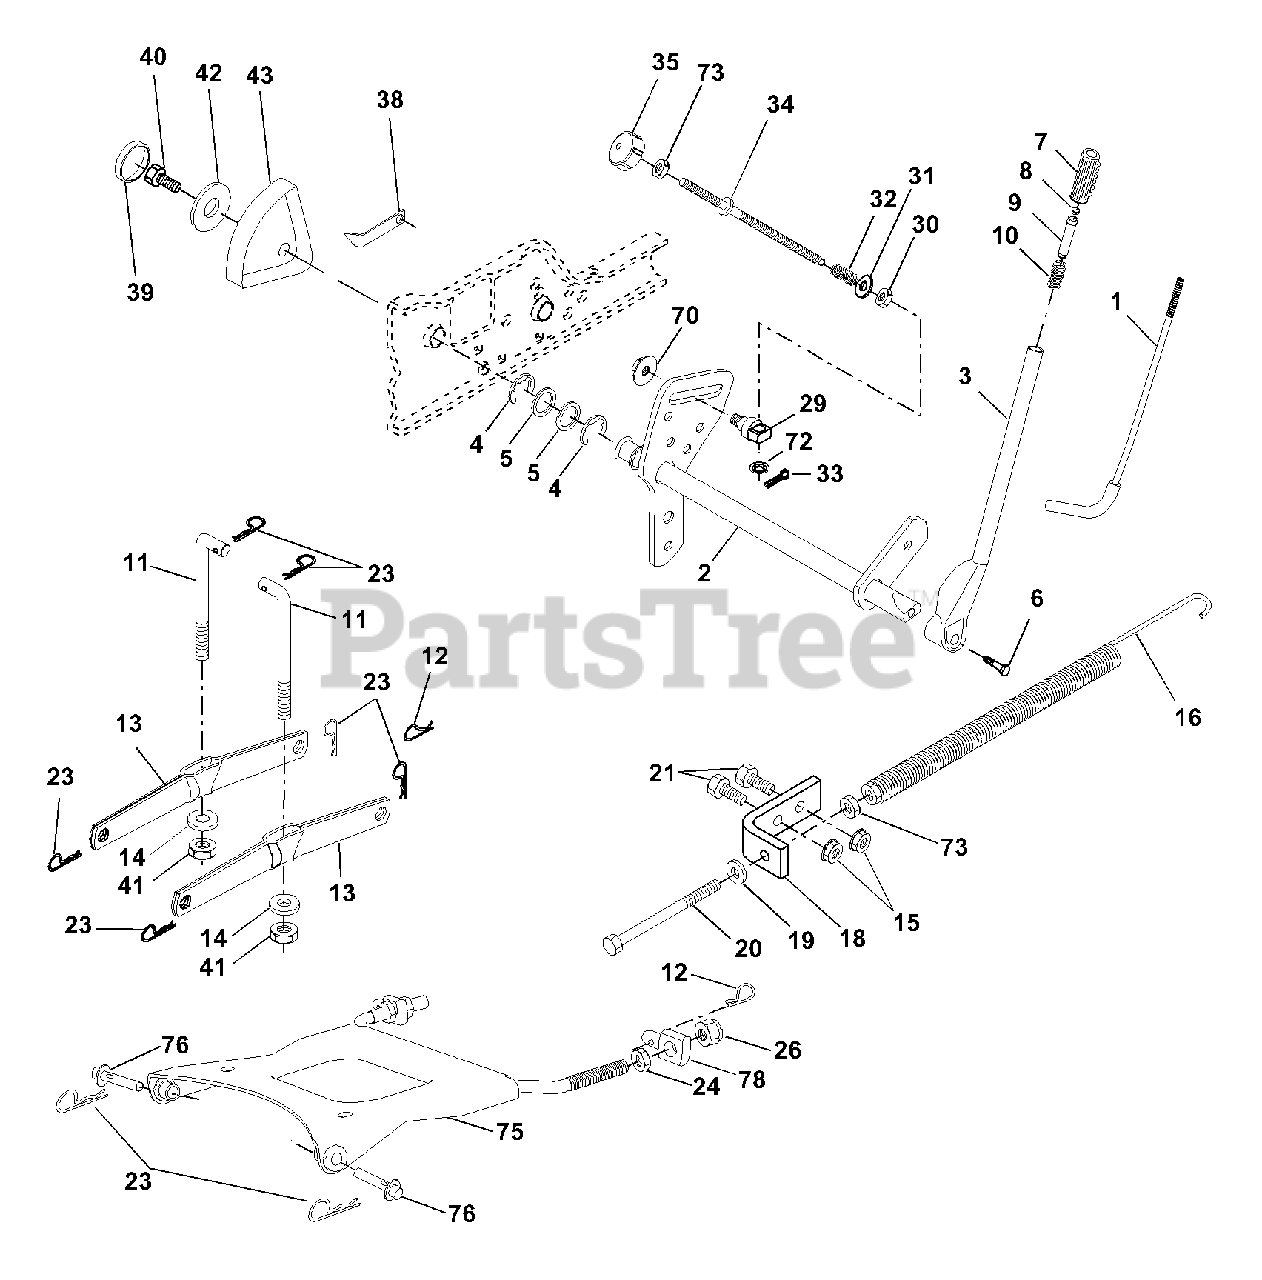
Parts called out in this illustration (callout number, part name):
1	Rod Asm., Lever
2	Shaft Asm., Lift Vgt
3	Lever Asm., Lift Rh
4	E-Ring Truarc #5133-87
5	Washer 29/32 x 1-1/4 x 16 Ga.
6	Bolt, Fin Hex 3/8-16 x 1-1/2
7	Grip, Handle
8	Button, Plunger
9	Plunger, Lever Lift
10	Spring 2-1/8"
11	Link Lift
12	Retainer, Spring
13	Arm, Suspension Vgt
15	Nut, Crownlock 3/8-16
16	Spring Asm., Assist Lift
18	Bracket, Spring Assist
19	Washer 13/32 x 13/16 x 16 Ga.
20	Bolt, Adjust Spring Assist
21	Bolt, Fin Hex 3/8-16 x 1
22	Link, Front
23	Retainer, Spring
24	Nut, Jam Hex 1/2-13 Unc
26	Nut, Lock W/Wsh 1/2-13 Unc
29	Trunnion Infin Height
30	Nut, Special
31	Washer 13/32 x 5/8 x 16 Ga.
32	Spring, Compression Inf Hgt
33	Pin, Cotter 3/32 x 1/2
34	Rod, Adj Lift
35	Knob, Inf 3/8-16 Unc
38	Pointer Height Indicator
39	Plug, Hole Blk. 1.485/1.515 Dia.
40	Screw 5/16-18 x 1
41	Nut, Crownlock 3/8-24
42	Washer 11/32 x 1-1/2 x 10 Ga.
43	Scale, Indicator Height
70	Nut Hex Flange Lock
72	Nut Push Phos & Oil
73	Nut Hex Jam 3/8-16
75	Plate Asm Sups. Front
76	Pin Flange
78	Trunnion Front Susp.
